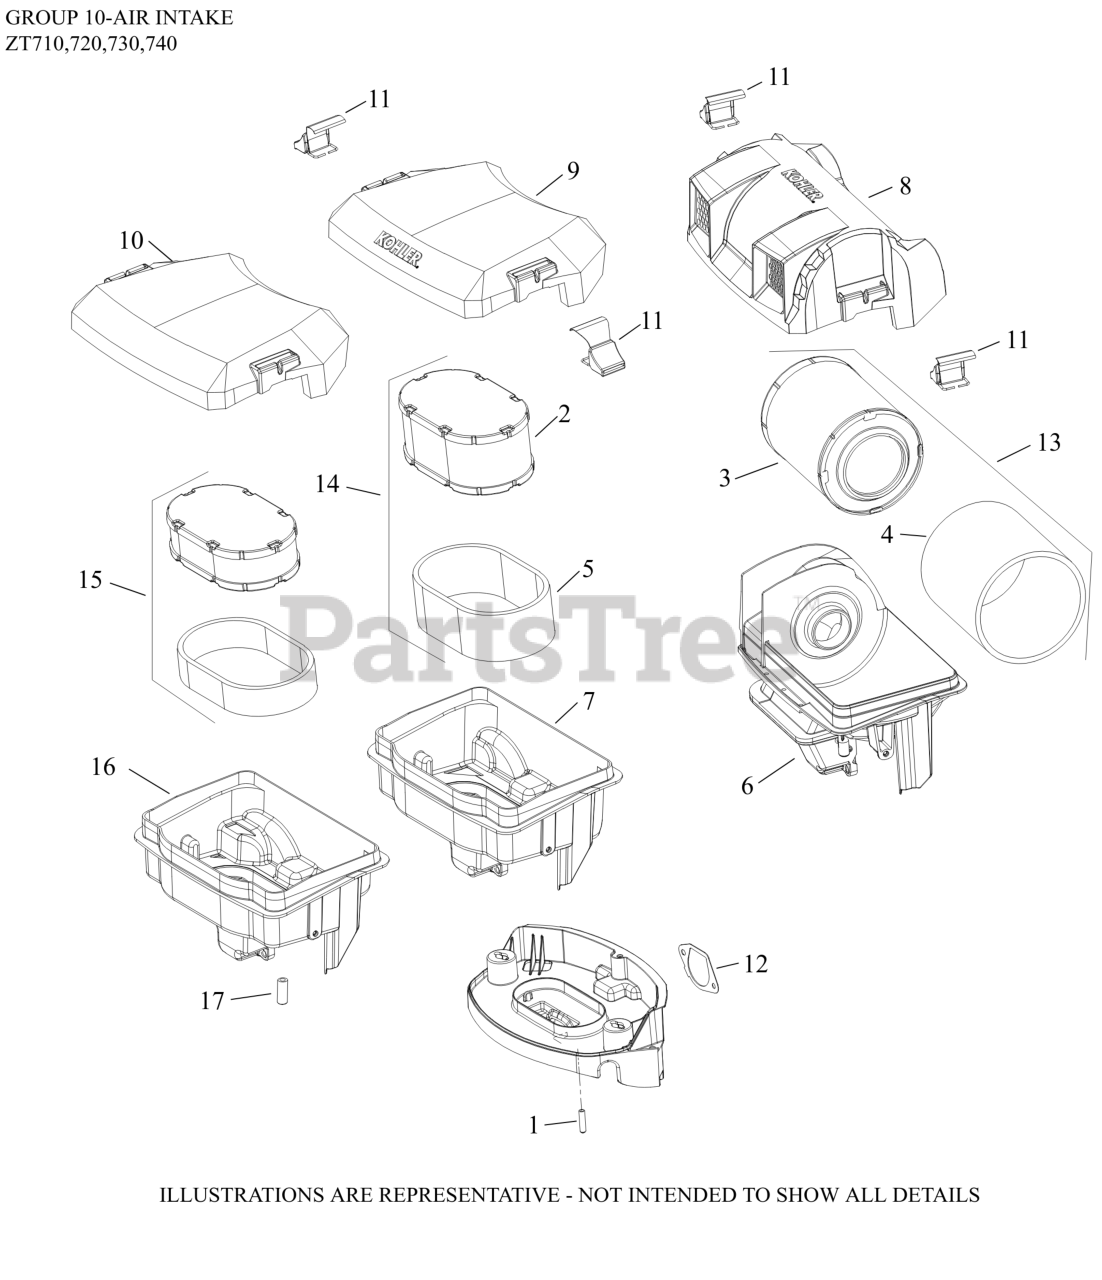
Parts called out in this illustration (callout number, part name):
1	CAP, MASKING
3	ELEMENT, AIR FILTER
4	ELEMENT, PRE-CLEANER
6	BASE ASSEMBLY, AIR CLEANER (HDAC)
8	COVER, AIR CLEANER (HDAC)
11	LATCH ASSY, AIR CLEANER COVER
12	GASKET, AIR CLEANER BASE
